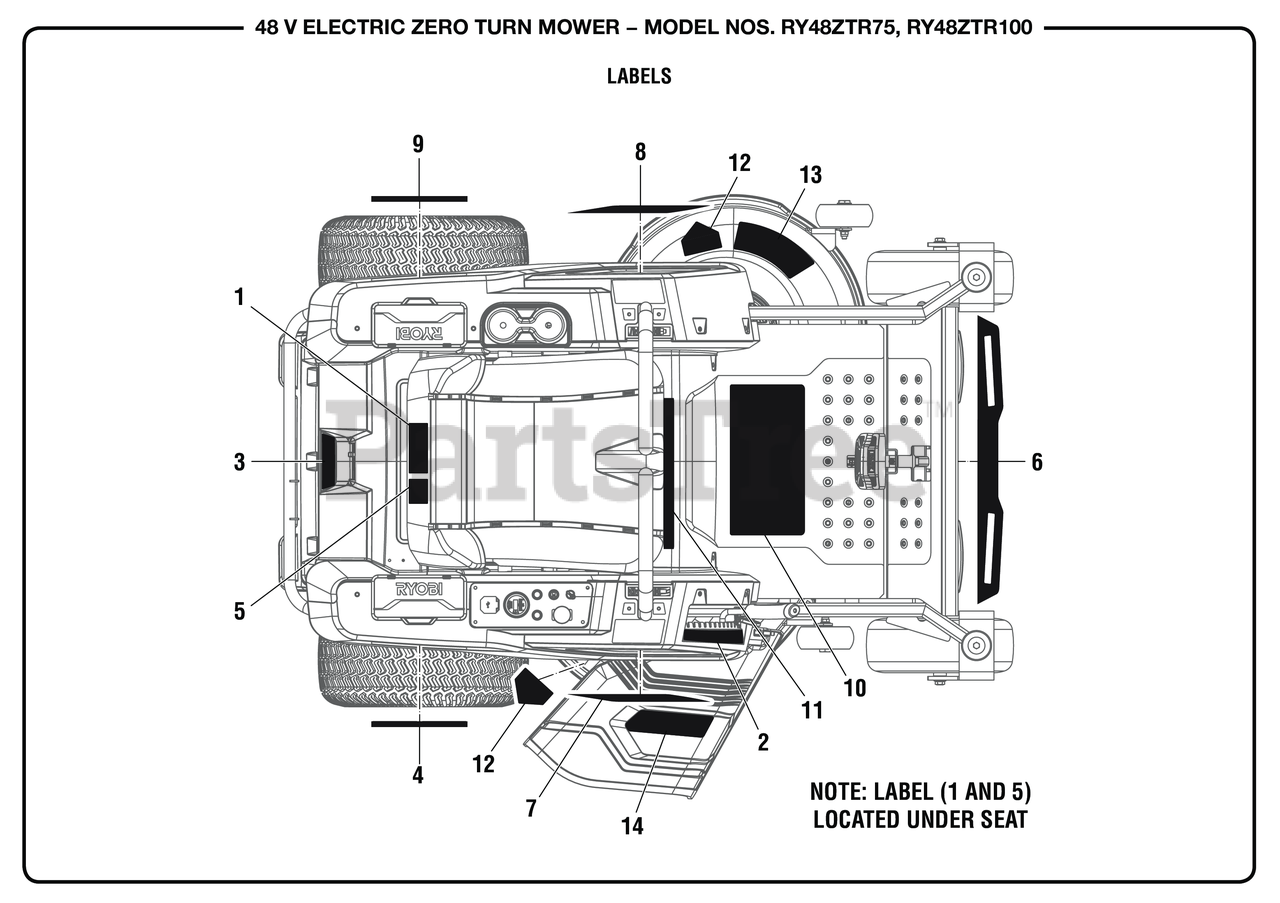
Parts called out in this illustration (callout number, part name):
1	DATA LABEL (RY48ZTR100)
2	DECK LIFT LABEL
3	CHARGING PORT LABEL, ENGLISH
3	CHARGING PORT LABEL, SPANISH
4	SUBBRAND LABEL, RIGHT (RY48ZTR100)
5	RPL LABEL, ENGLISH
5	RPL LABEL, SPANISH
6	RYOBI LABEL, FRONT
7	RYOBI LOGO, RIGHT
8	RYOBI LABEL, LEFT
9	SUBBRAND LABEL, LEFT (RY48ZTR100)
10	FLOOR DANGER LABEL, ENGLISH
10	FLOOR DANGER LABEL, SPANISH
11	INSTRUCTION LABEL, ENGLISH
11	INSTRUCTION LABEL, SPANISH
12	No Hands CPSC Danger Label, English
12	No Hands CPSC Danger Label, Spanish
13	Deck Danger Label, English
14	Discharge Danger Label, English
14	Discharge Danger Label, Spanish
